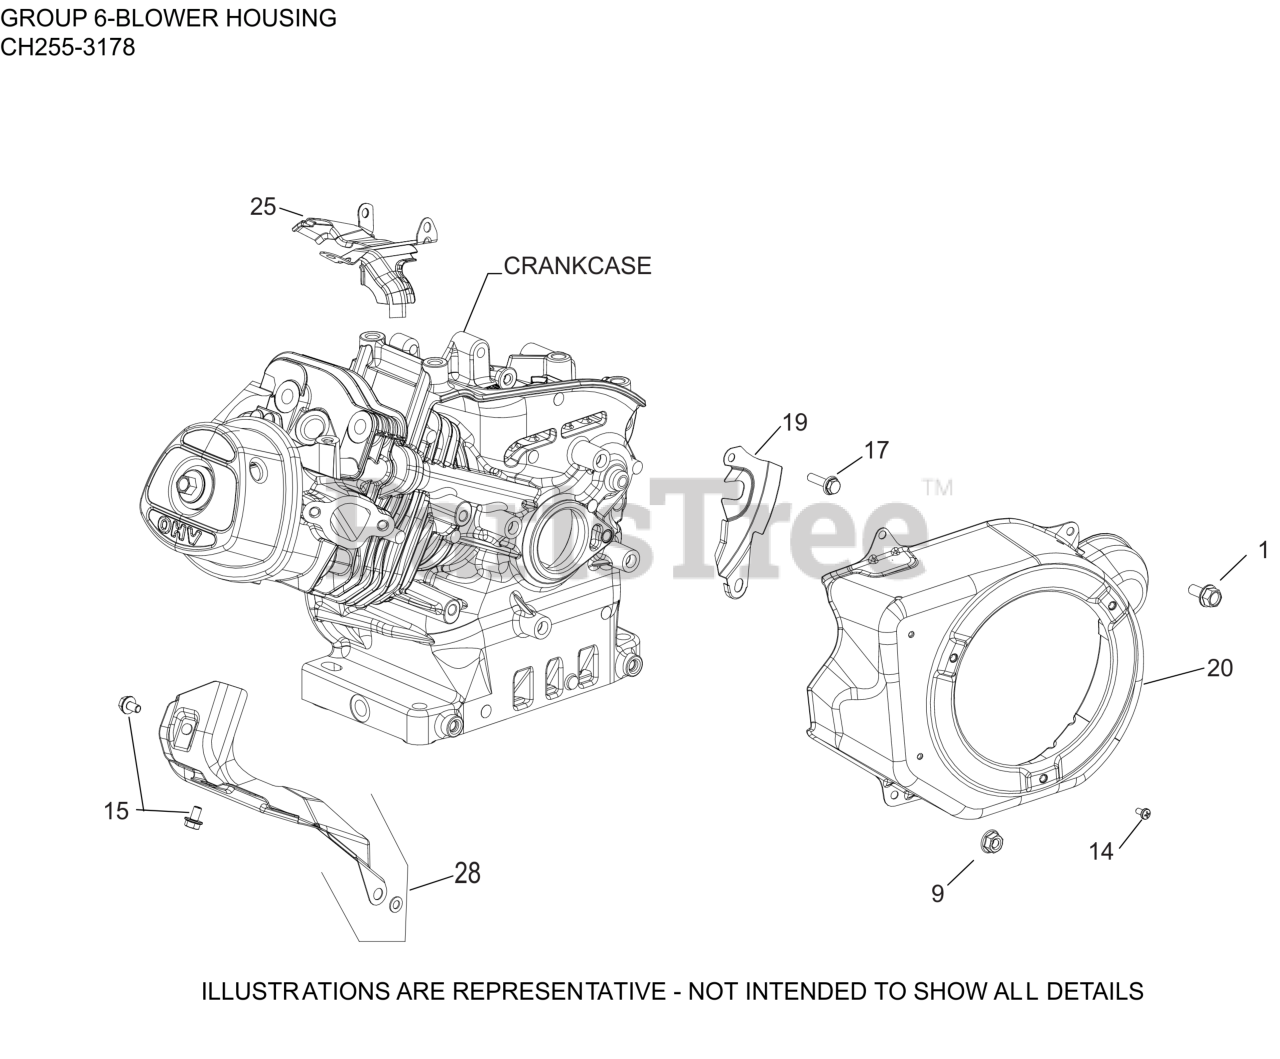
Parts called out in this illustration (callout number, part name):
1	SCREW, HEX FLANGE (M6)-USE 25 086 433-S
9	NUT, HEX FLANGE (M6) - USE 14 100 16-S
14	SCREW, COVER TO BLOWER HOUSING
15	SCREW, HEX FLANGE (M6)
17	SCREW, M6 X 22
19	SHIELD, FLYWHEEL ASSEMBLY
20	KIT, BLOWER HOUSING
25	FLOW SHIELD
28	KIT, CYLINDER SHIELD
